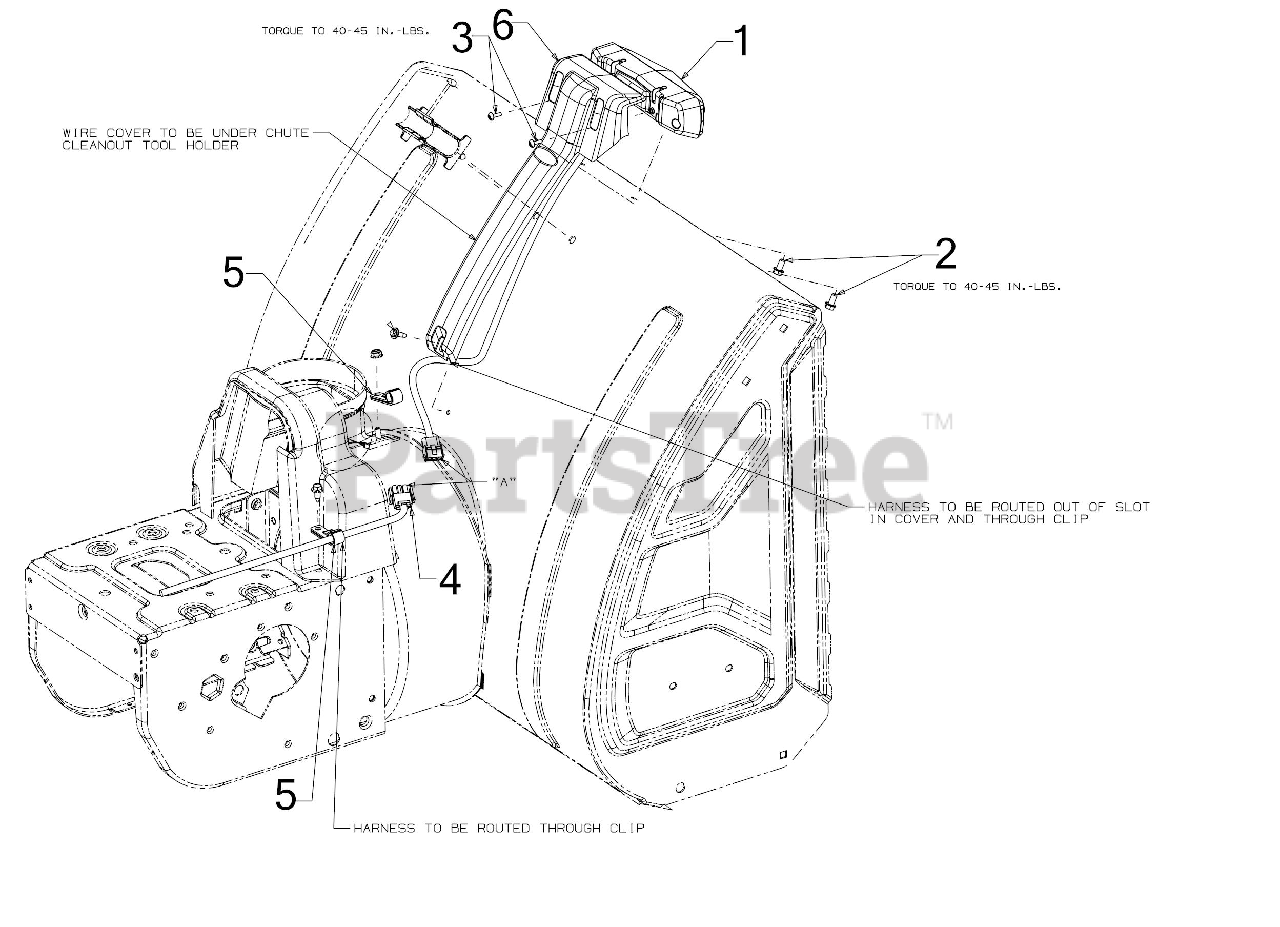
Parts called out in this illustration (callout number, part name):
1	LED LIGHT BAR HEADLIGHT ASSEMBLY
2	HEX SCREW 1/4-15 x .50
3	SCREW 8/16 x .500
4	LED HEADLIGHT HARNESS
5	HEADLIGHT HARNESS CLAMP
6	LED LIGHT BAR COVER
